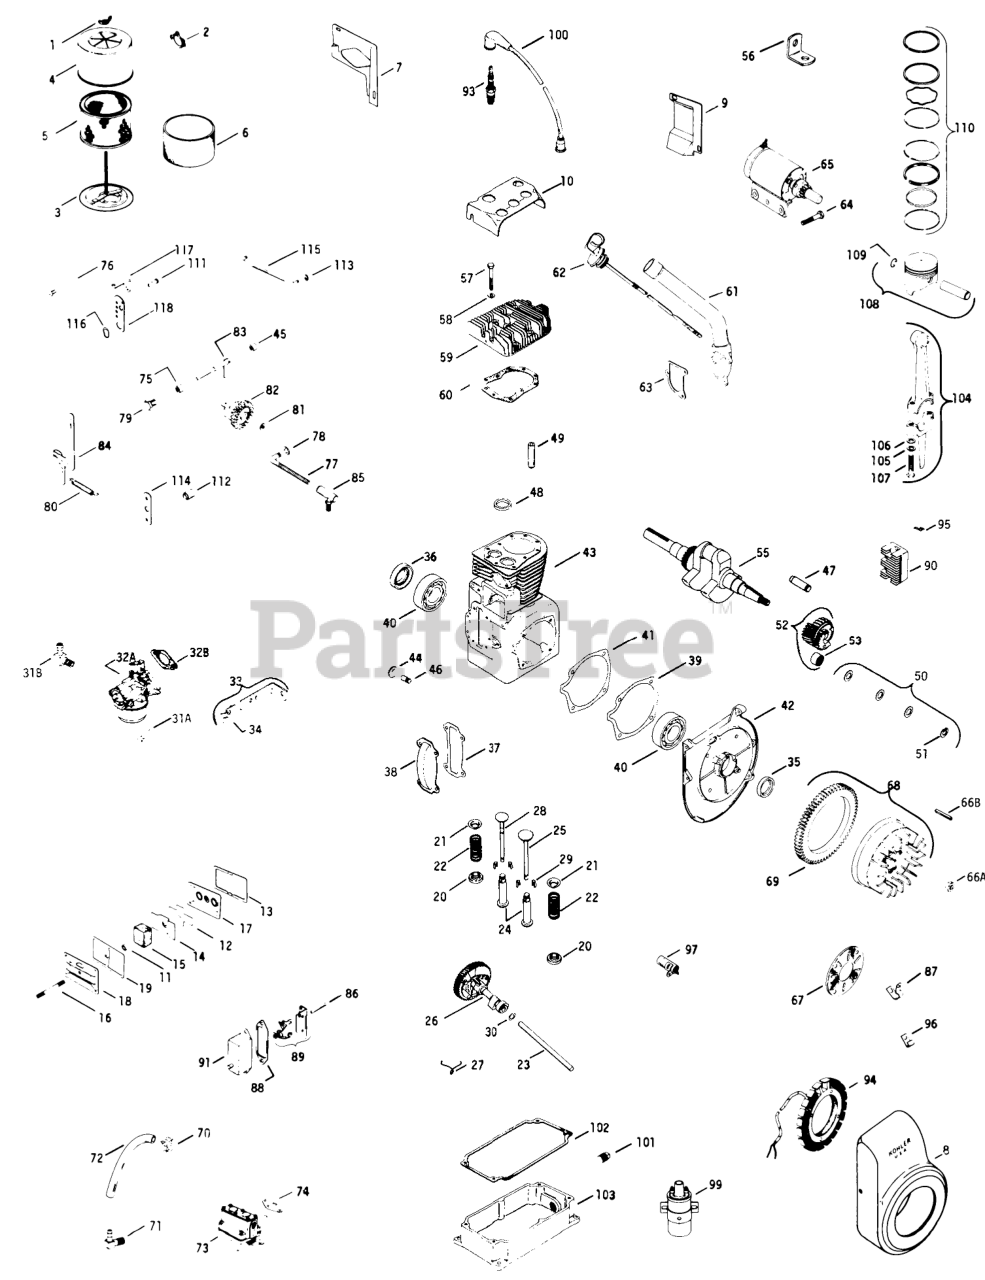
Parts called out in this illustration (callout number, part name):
1	Nut-Wing
2	Gasket, air horn
3	Base-Air Cleaner
4	Cover-Air Cleaner
5	Element
6	Element
7	BaffLe side air
8	Housing-Blower
9	Baffle, cylinder
10	Baffle, head
11	Seal
12	Reed
13	Gasket
14	Baffle breather
15	Filter Breather
16	Stud, valve cover
17	Plate
18	Cover valve
19	Gasket
20	Rotator
21	Retainer-Spring
22	Spring
23	Pin (Service)
24	Tappet
25	Valve-Intake
26	Camshaft-assembly
27	Spring-Actuating
28	Valve exhaust
29	Keeper, Valve
30	Spacer
31A	Screw sitd. hd.
31B	Elbow
32A	Carburetor-assembly
32A	Repairkit
32B	Gasket
33	Bracket, choke
34	Clip
35	Seal, Front OiI
36	Seal rear oil
37	Gasket
38	Cover
39	Gasket
40	Ball Bearing
41	Gasket
42	Plate Bearing
43	Block, cylinder-assembly (Use 45_782_02 Miniblock)
44	Plug
45	Bearing
46	Shaft-Govemor
47	Shaft
48	Insert
49	Guide Valve
50	Kit-Spacer
51	Retainer
52	Gear
53	Bearing,needle
55	Crankshaft
56	Lift Cable
57	Screw
57	Screw-H.C.
58	Washer
59	Head, cylinder
60	Gasket, head
61	Tube, fill
62	Dipstick
63	Gasket
64	Screw
65	Starter-assembly
65	Kit, Brush & Spring
65	Washer
66A	Nut
66B	Key
67	Screen grass
68	Flywheel-assembly
69	Gear Ring
70	Clamp
71	Elbow
72	Line Fuel
73	Pump, fuel
74	Gasket, pump
75	Spacer
76	Pin-GovemorStop
77	Rod ball joint
78	Retainer Rod
79	Bushing
80	Spring-Governor
81	Washer
82	Gear, Governor
83	Shaft, Governor
84	Lever, governor
85	Ball joint
86	Rod, breaker
87	Clip
88	Gasket, Cover
89	Breaker
90	Regulator
91	Cover breaker
93	Plug, spark
94	Stator
95	Connector
96	Clip
97	Condenser
99	Coil
100	Kit, Hi-Tension
101	Plug
102	Gasket
103	Base, oil pan
104	Rod, conn.-assembly Std.
105	Washer
106	Washer
107	Screw, connecting rod
108	Piston-assembly (Std.)(Includes pin & retainers)
108	Piston-assembly (.003)(Includes pin & retainers)
108	Piston-assembly (.010)(Includes pin & retainers)
108	Piston-assembly (.020)(Includes pin & retainers)
108	Piston-assembly (.030)(Includes pin & retainers)
109	Pin, Retainer
110	Ring set-Std. & .003
110	Ring set-.010
110	Ring set-.020
110	Ring set-.030
111	Clamp, swivel wire
112	Spacer
113	Retainer Rod
114	Bellcrank
115	Rod, throttle
116	Washer
117	Spacer
118	Bracket
118	Gasket Set
118	Miniblock
118	Shortblock
118	Service Engine
